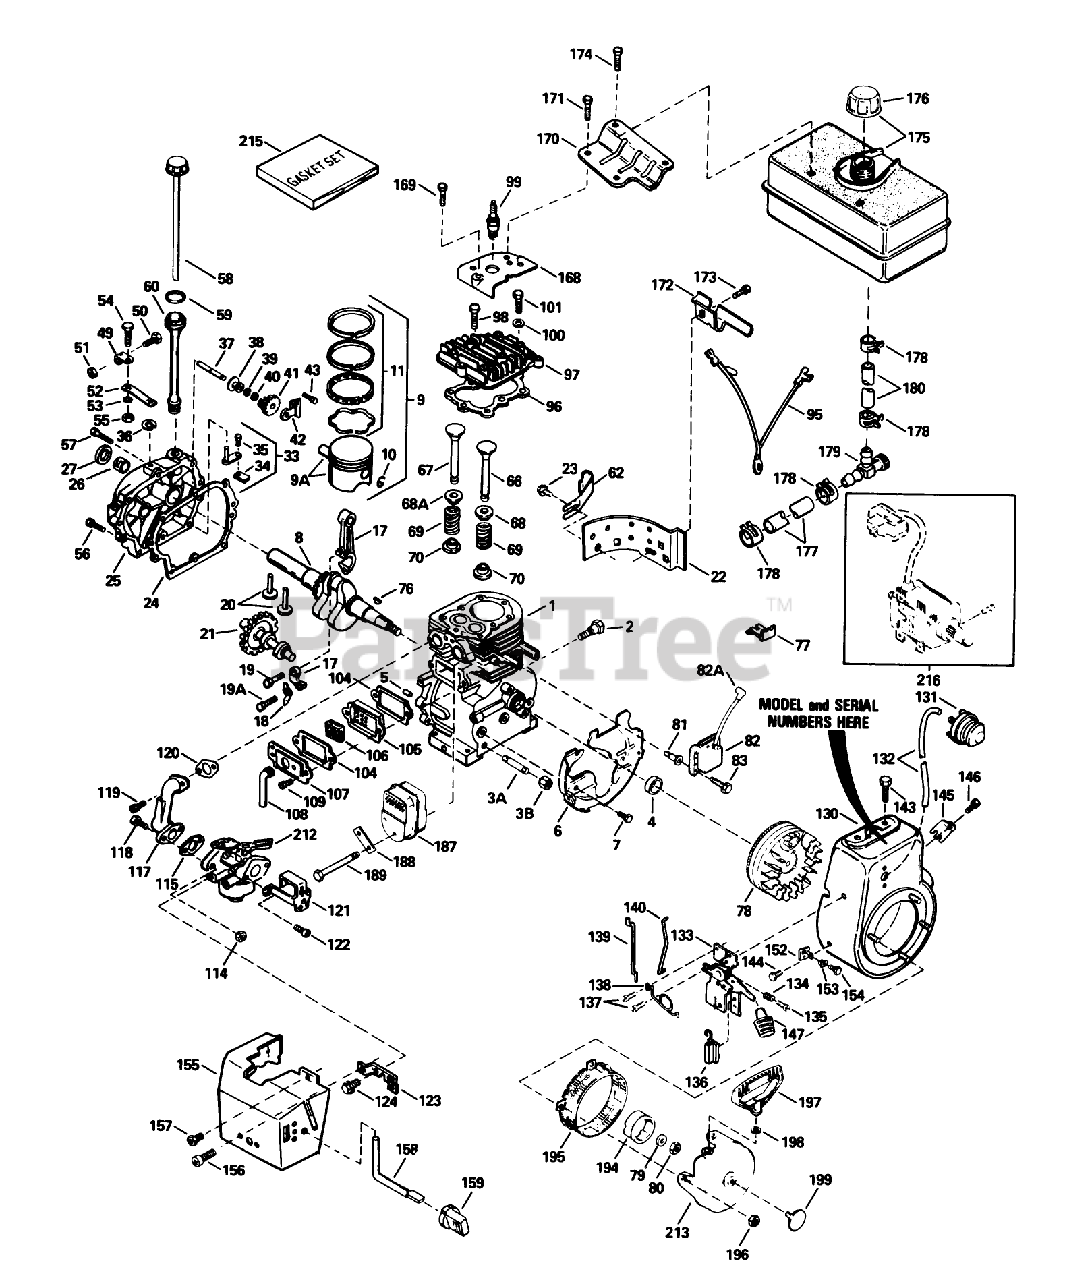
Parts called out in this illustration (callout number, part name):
1	Cylinder Asm (Includes 2, 20, 72)
2	Screw (1/4-20x1/2)
3A	Nipple-Pipe
3B	Cap-Pipe
4	Seal-Oil
5	Pin-Dowel
6	Baffle-Blower Housing
7	Screw (1/4-20x19/32)
8	Crankshaft
9	Piston, Pin Ring Assy.(Std.) (Incl. Ref. #24A, 25 26)
9A	Piston Pin Assy. (Std.) (Incl. Ref. #26)
11	Ring Set (Std.)
17	Rod Assy., Connecting (Incl. Ref. #28 28A)
18	Dipper-Oil
19	Bolt-Rod
19A	Bolt-Rod
20	Lifter-Valve
21	Camshaft (MCR)
22	Extension-Housing, Blower
23	Screw
24	Cylinder Cover Gasket
25	Cover-Cylinder (Includes 71, 75, 80)
26	2025A77 WIZARD ROTA
27	Seal-Oil
33	Rod, Governor (Incl. Nos.62 63)
34	Yoke-Governor
35	Screw (6-40x5/16)
36	Ring-Retaining
37	Shaft-Governor
38	Spool-Governor
39	Washer-Flat
40	Ring-Retaining
41	Gear Assy., Governor (Incl. Ref. #45)
42	Bracket-Gear, Governor
43	Screw (10-24x1/2)
49	Clamp-Lever, Governor
50	Screw
51	Nut-Lock
52	Lever-Governor
53	Washer-Lock
54	Screw
55	Nut-Lock
56	Screw (1/4-20x1-11/16)
57	Screw (1/4-20x1-3/16)
58	Dipstick
59	O-Ring
60	Tube-Fill, Oil
62	Clip-Tube, Fill
66	Valve, Exhaust (Standard)(Incl. No. 9)
67	Valve, Intake (Std.) (Incl. Ref. #58)
68	Cap-Spring, Valve
68A	Seal-Intake Valve
69	Spring-Valve
70	Keeper-Spring, Valve
76	Key-Flywheel
77	Clip-Wire
78	Flywheel (W/Ring Gear)
79	Washer-Belleville
80	Nut-Flywheel
82	Solid State ASM
82A	Cover-Spark Plug
83	Screw
95	Ground Wire
96	Gasket-Cylinder Head
97	Head Cylinder
98	Screw (5/16-18x1-1/2)
99	Spark Plug-Resistor (R J19 L M)
100	Washer-Flat
101	Screw (5/16-18x1-25/32)
104	Gasket-Breather
105	Body-Breather
106	Element-Breather
107	Cover-Valve
108	Tube-Breather
109	Screw
114	Nut and Lock Washer (1/4-28)
115	Gasket-Carburetor To Intake Pipe
117	Pipe-Intake
118	Screw (1/4-28x1)
119	Screw (T-30, 5/16-18x1-3/32)
120	Gasket-Intake
121	Bracket-Choke
122	Screw (10-32 x 1/2)
123	Bracket-Carburetor
124	Screw (8-32x27/64)
130	Housing-Blower
131	Primer-Asm
132	Line-Primer
133	Control Assy., Remote Speed (Incl. Ref. #90 thru 93)
134	Spring-Compression
135	Screw
136	Terminal
137	Screw (10-32 x 1/2)
138	Spring-Throttle
139	Link-Governor
140	Link-Throttle
143	Screw (5/16-18x3/4)
144	Screw
145	Screw
146	Screw (8-32 x 3/8)
147	Knob-Control
152	Bracket
153	Grommet
154	Screw (8-32 x 3/8)
155	Cover-Carburetor
156	Screw (10-32 x 3/8)
157	Screw (10-32x1/2)
158	Rod-Choke
159	Knob-Control
168	Cover-Cylinder Head
169	Screw (1/2-20x5/8)
170	Bracket-Tank, Fuel (Black)
171	Screw
172	Bracket-Tank, Fuel
173	Screw (1/4-20x19/32)
174	Screw (1/4-15x7/8)
175	Tank-Fuel (Includes 292, 301)
176	Cap-Fuel
177	Line-Fuel
178	Clamp-Line, Fuel
179	Valve-Shut Off
180	Line-Fuel (8.62)
187	Muffler
188	62513 SNWTHWR W/284
189	Screw
194	Cup-Starter
195	Screen-Starter
196	Nut and Lock Washer (1/4-28)
197	Handle-Starter, Mitten Grip
198	Washer
199	Plug Starter
212	Carburetor (Incl. Ref. #75)
213	Starter-Rewind
215	Gasket Set (Incl. items marked *) Order As Accessory.
